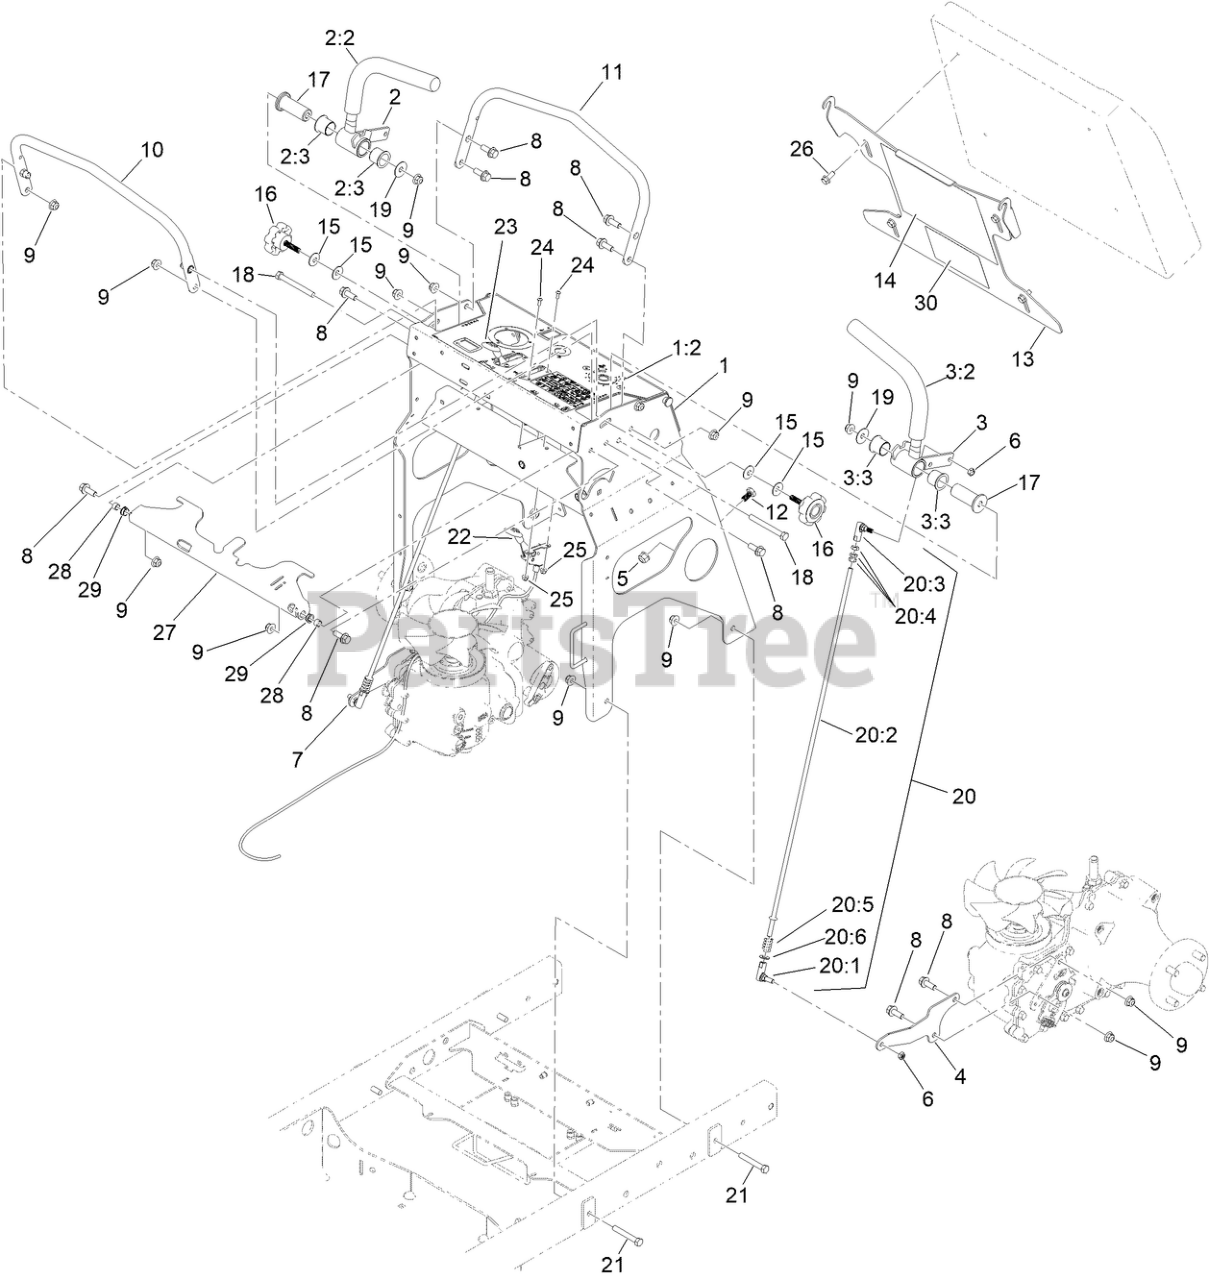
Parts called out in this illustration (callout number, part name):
1	TOWER-ASM W/DECAL
1:2	DECAL-CONTROL PANEL
2	HANDLE-CONTROL, RH ASM
2:2	GRIP-CONTROL, MOTION
2:3	BUSHING-PIVOT
3	HANDLE-CONTROL, LH ASM
3:2	GRIP-CONTROL, MOTION
3:3	BUSHING-PIVOT
4	PLATE-CONTROL, LH RTN
5	NUT-LOCK, NI
6	NUT-LOCK, NI
7	PLATE-CONTROL, RH RTN
8	SCREW-HHF
9	Nut-Hex Flange
10	BAR-SPEED, ASM
11	BAR-REFERENCE
12	MAGNET-STUD, THREADED
13	PLATE-KNEE PAD
14	DECAL-SPRAY CHART
15	WASHER-SPRING
16	KNOB-FLUTED
17	PIVOT-CONTROL, HANDLE
18	HHCS,3/8-16X3-1/2,ST/ST 18-8
19	WASHER-FLAT
20	LINKAGE-CONTROL ASM
20:1	Balljoint-SS
20:2	ROD-CONTROL, MOTION
20:3	3/8-24 SS BALL JOINT\N367
20:4	Nut-Hex
20:5	SPRING-COMPRESSION
21	HHCS,3/8-16X2-1/2,ST/ST 18-8
22	CONTROL-CHOKE
23	CONTROL-THROTTLE
24	Screw-HSBH
25	Nut-Hex Flange
26	SCREW-HHF
27	PLATE-LOCK, MC
28	SPACER-BRAKE PIVOT
29	BUSHING,SNAP
30	DECAL-SERVICE AID
